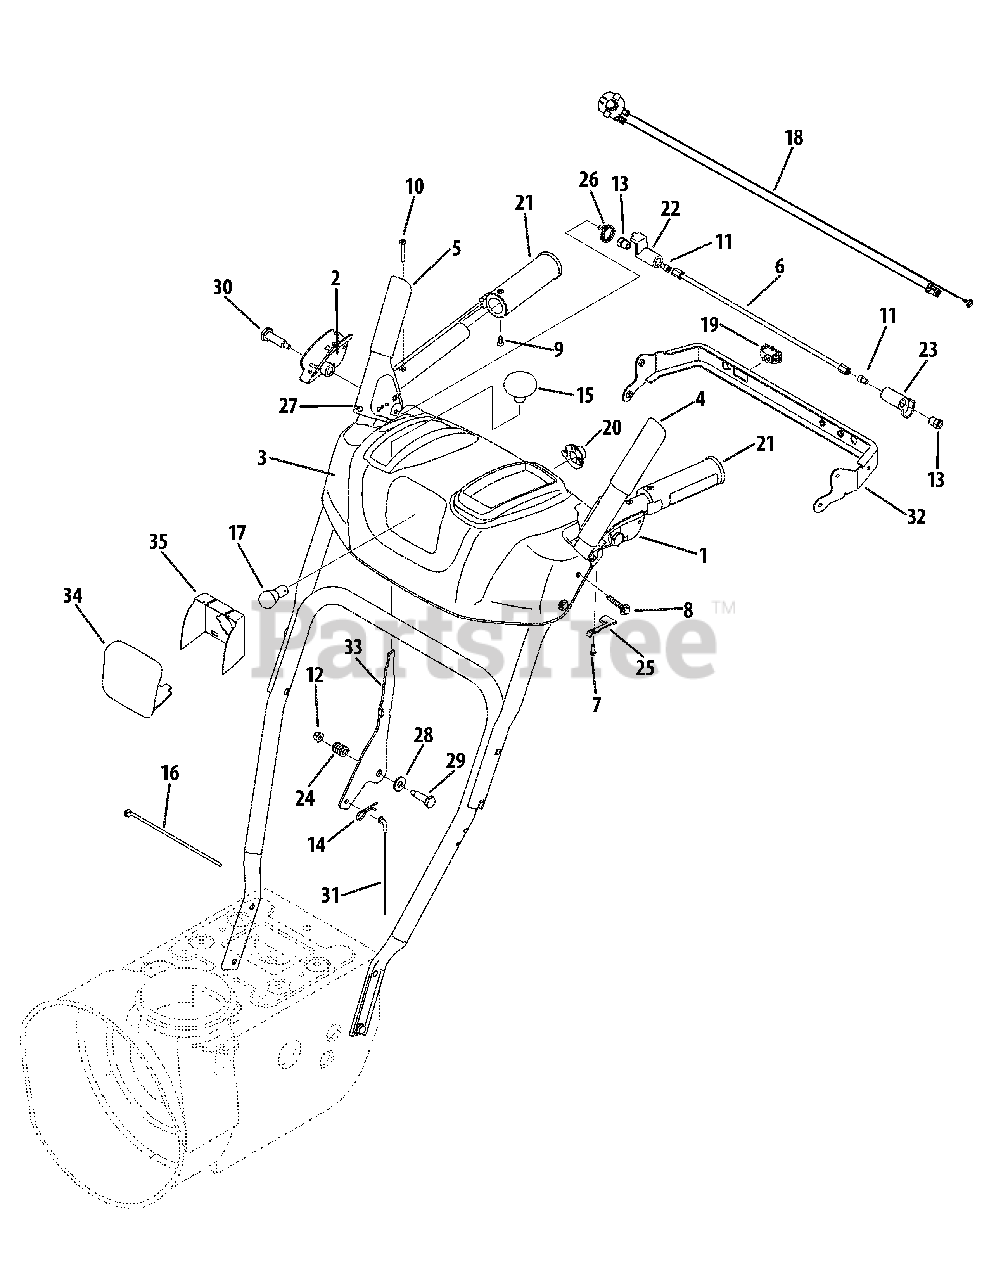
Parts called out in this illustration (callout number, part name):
1	Clutch Lock Handle Assembly, LH
2	Clutch Lock Handle Assembly, RH
3	Handle Panel
4	Engagement Assembly, LH
5	Engagement Assembly, RH
6	Clutch 736- Lock Rod Assembly
7	Hex Washer Screw, #8-16 x .50
8	Hex Washer Screw, 1/4-20 x 1.625
9	Screw, #10-16 x .625
10	Machine Screw, #10-24 x 1.375
11	Socket Screw, 1/4-20 x .50
12	Flange Lock Nut, 1/4-20
13	Hex Nut, 1/4-20
14	Click Pin, .092 x 1.64
15	Shift Knob
16	Cable Tie
17	Lamp
18	Wire Harness
19	Heated Grip Switch
20	Nylon Socket
21	Heated Grip
22	Lock Plate
23	Clutch Lock Cam
24	Compression Spring, .39 x .60 x .88
25	Clutch Lock Spring
26	Torsion Spring, .8156 ID x .3038
27	Rubber Bumper, .62 OD x .22 Thick
28	Flat Washer, .385 x .87 x .06
29	Shoulder Screw, .374 Dia. x 1.05 LG.
30	Shoulder Screw, .437 x 1.345 x 1/4-20
31	Speed Selector Cable
34	Headlight Lens
35	YM Lens Label
